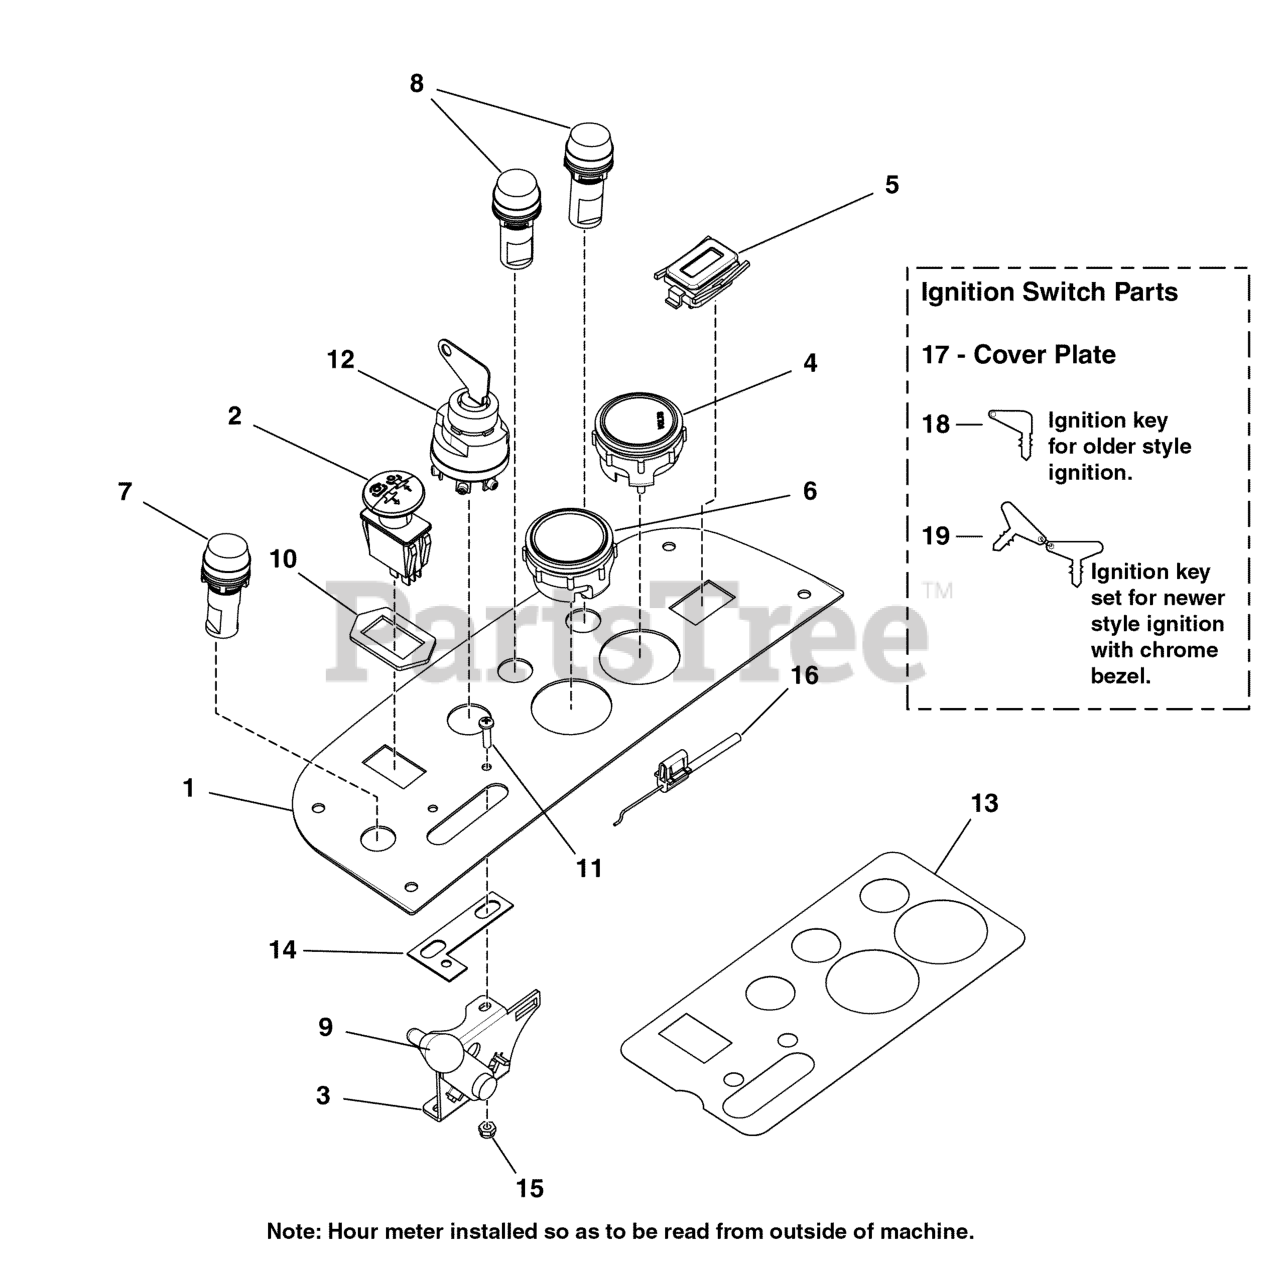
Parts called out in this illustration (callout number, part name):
1	CONTROL PANEL, IS5000Z RH - BLK
2	SWITCH, BLADE ENGAGEMENT
3	HANDLE, THROTTLE CONTROL
4	GUAGE, VOLTS
5	HOUR METER
6	GAUGE, WATER TEMPERATURE
7	LIGHT, GLOW PLUG, 22MM AMBER
8	LIGHT, WARNING, 22MM RED
9	THROTTLE CONTROL HANDLE/KNOB
10	RING, SWITCH RETAINER
11	SCREW, #10-24 X 3/4"
12	SWITCH, Ignition, Complete
13	DECAL, CONTROL PANEL
14	PLATE, THROTTLE STOP
15	NUT, #10-24 HEX NYLON LOCK
16	CABLE, THROTTLE CONTROL, 47.5"
19	KEY, SET OF TWO, IGN SWITCH, CAT ENG
